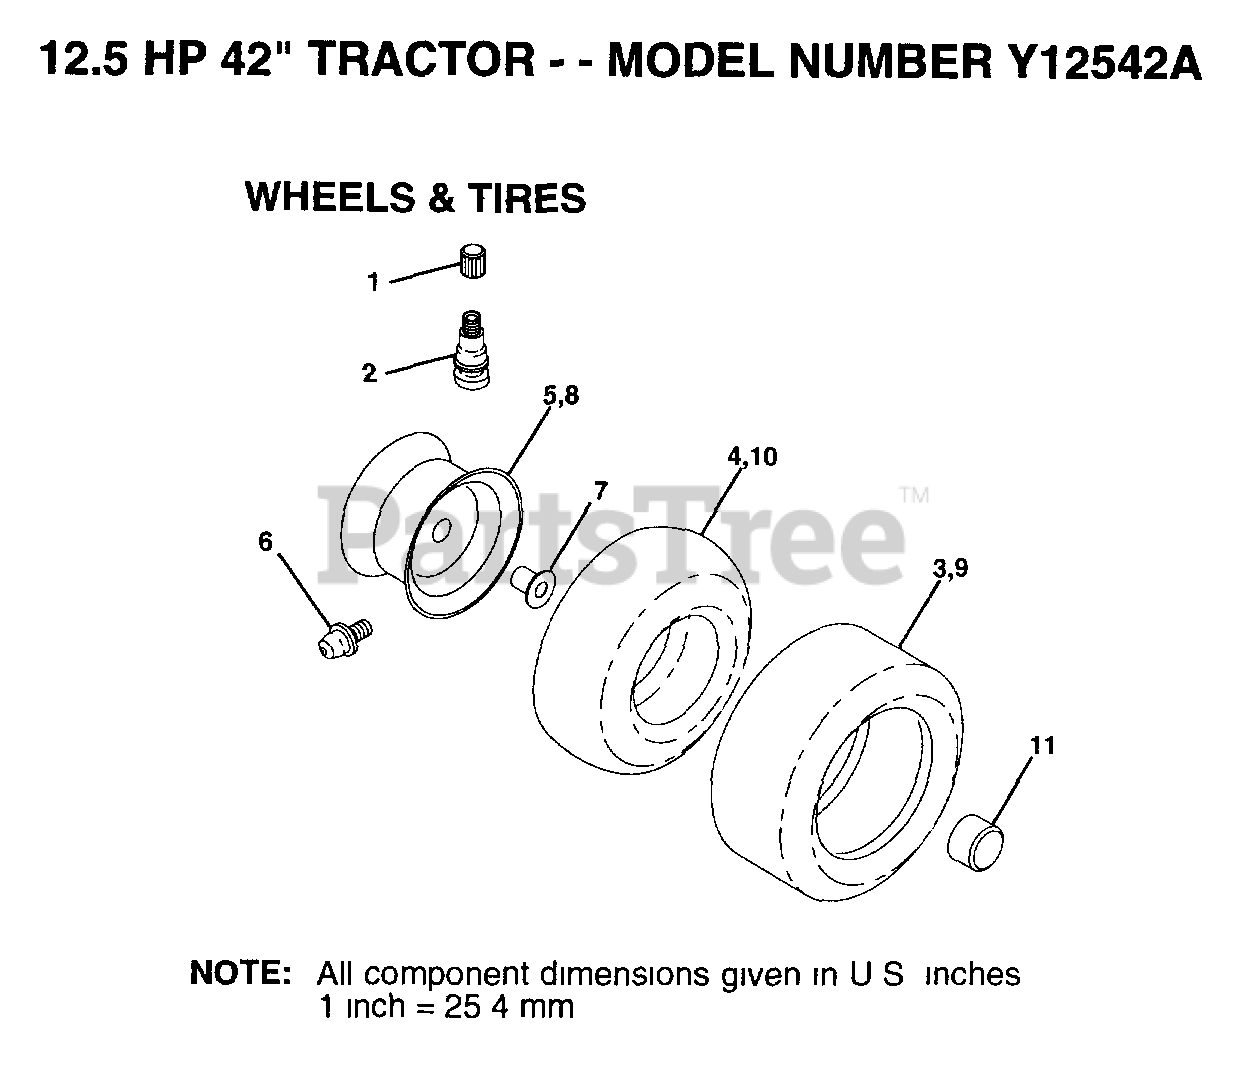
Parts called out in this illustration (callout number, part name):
1	VALVE CAP
2	VALVE STEM LT
4	TUBE.5.3/4.5/6
6	FITTING LT
7	"FLANGE, BEARING"
10	TUBE.18X9.5-8
11	HUB CAP
